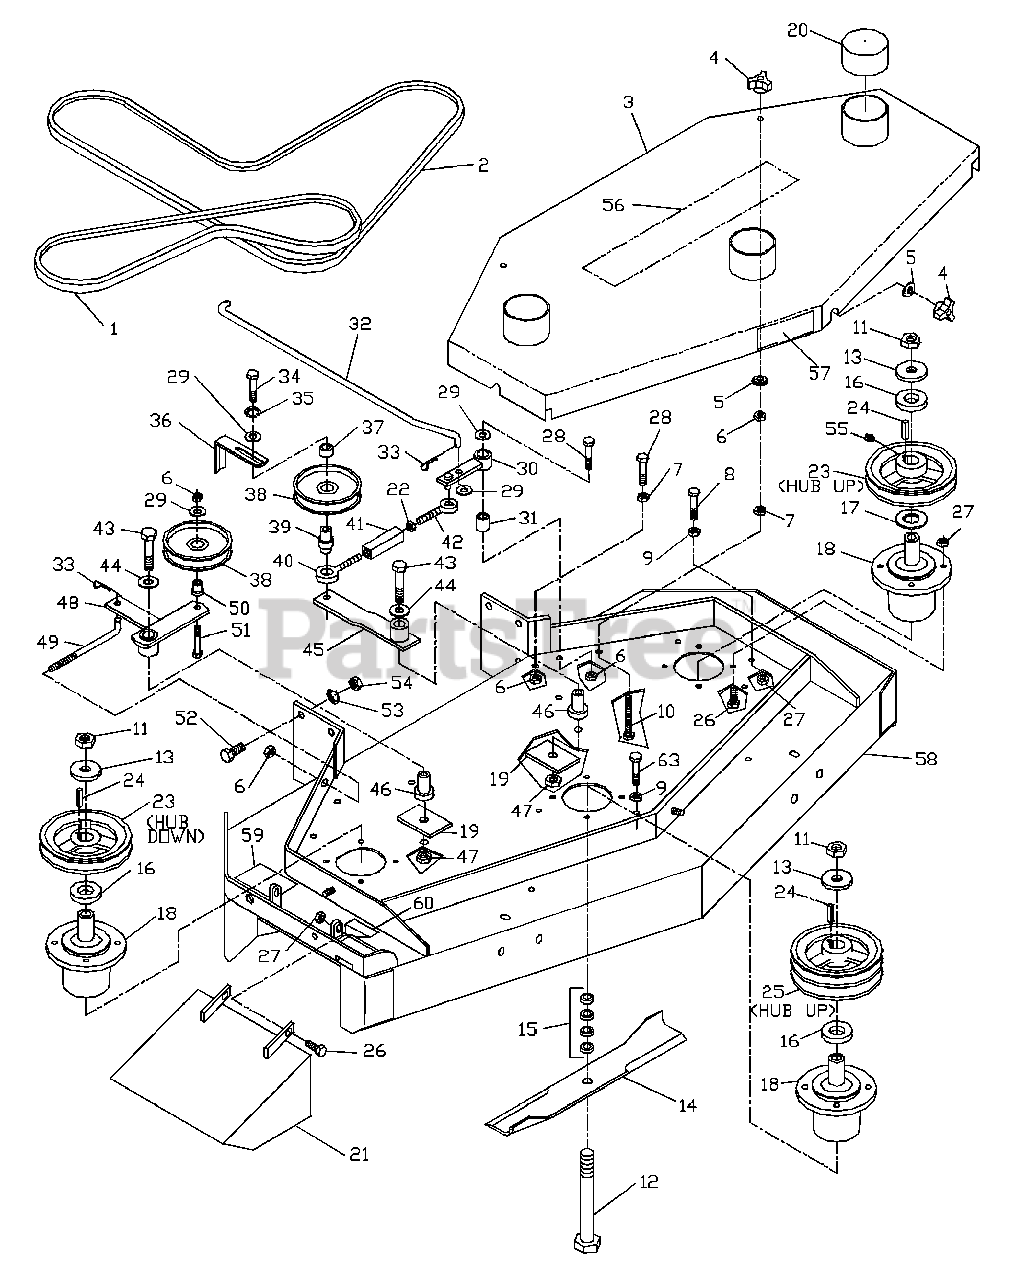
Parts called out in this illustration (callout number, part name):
1	AUX. BLADE BELT
2	BLADE BELT 48
3	48" BELT SHIELD
4	THREE PRONG KNOB
5	3/8 SEALING WASHER
8	HCS 5/16CX3(BELT GUIDE)
9	HFLN 5/16C
10	TAPBOLT-3/8C X 4 1/2
12	HCS 5/8F X 8 1/2
12	HCS 5/8F X 9(CENTER)
13	SUPPORT WASHER
14	BLADE 16 1/4"
15	BLADE SPACERS
17	MACH. BUSHING 10 GA.
18	HOUSING ASM.
21	DEFLECTOR CHUTE
22	5/16C HEX NUT
23	PULLEY W/SETSCREWS
24	1/4SQ. KEY X 1 1/8
25	DOUBLE PULLEY W/SETS.
26	HCS 5/16C X 1
28	HCS 3/8C X 2 1/4
29	FW 3/8 STD
30	ENGAGEMENT ARM
31	SLEEVE BUSHING
32	BLADE ROD 48"
33	#2 HAIRPIN
34	HCS 3/8C X 2 1/2
35	3/8 LOCK WASHER
38	IDLER PULLEY
39	EYEBOLT PIVOT
40	LEFT HAND EYEBOLT
41	TURNBUCKLE
42	RH. EYEBOLT
43	HCS 1/2C X 2 3/4
44	1/2 FLAT WASHER
46	IDLER SPINDLE
47	1/2C NYLOC NUT
48	AUX. IDLER ARM
49	TENSION ROD
50	IDLER FLANGE BUSHING
51	HCS 3/8C X 1 3/4
52	HCS 7/16C X 1 1/2
53	7/16 LOCK WASHER
54	7/16C HEX NUT
55	5/16 NYLOC SETSCREW
56	DECAL, HUSQVARNA
57	DECAL, NASCAR
58	48" DECK W/DECALS
59	DECAL, DANGER
60	DECAL, CPSC
63	HCS 5/16C X 4
